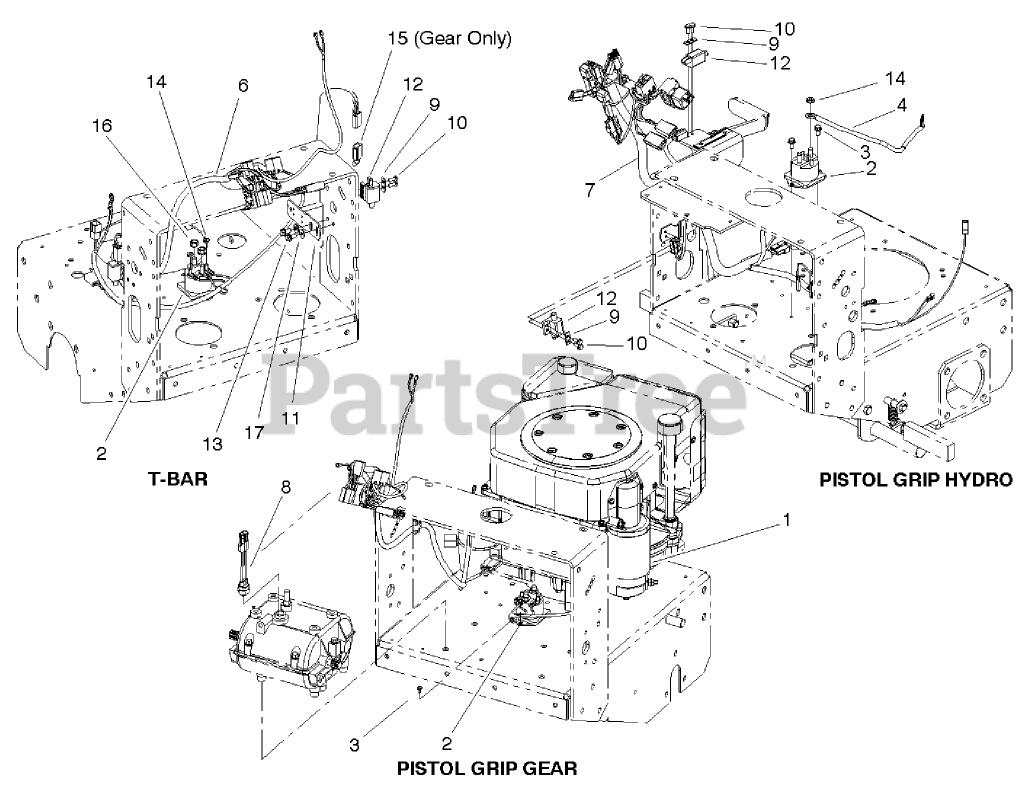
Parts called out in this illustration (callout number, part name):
1	Starter ASM (includes rectifier - 41 403 09)
2	SOLENOID
3	SCREW
4	WIRE-SOLENOID/STARTER
6	HARNESS-WIRE (T-BAR)
7	Harness-Wire
8	SWITCH-BALL
9	PLATE-SWITCH
10	SCREW-TAPTITE
11	Bracket-Neutral
12	SWITCH-POLE, SINGLE
13	SCREW-HWH
14	NUT-KEPS
15	Wire-Jumper ASM
16	NUT-KEPS
17	WASHER-FLAT
